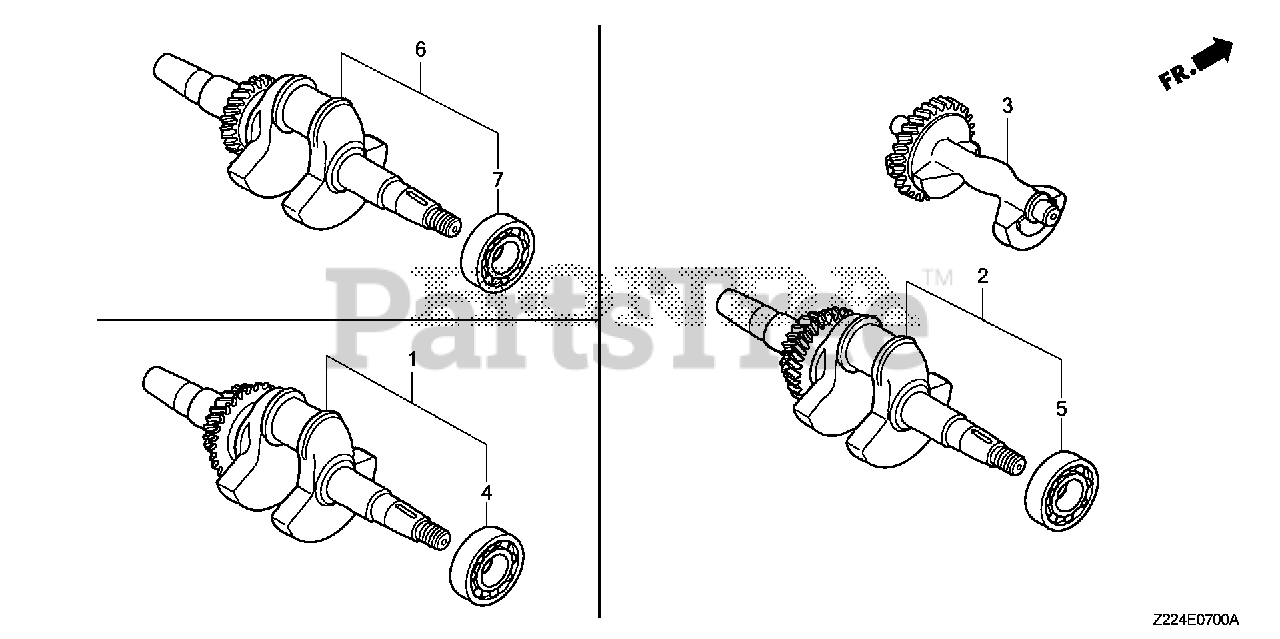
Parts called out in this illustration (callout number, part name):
2	CRANKSHAFT
3	WEIGHT, BALANCER
5	BEARING, RADIAL BALL (6207SH)
